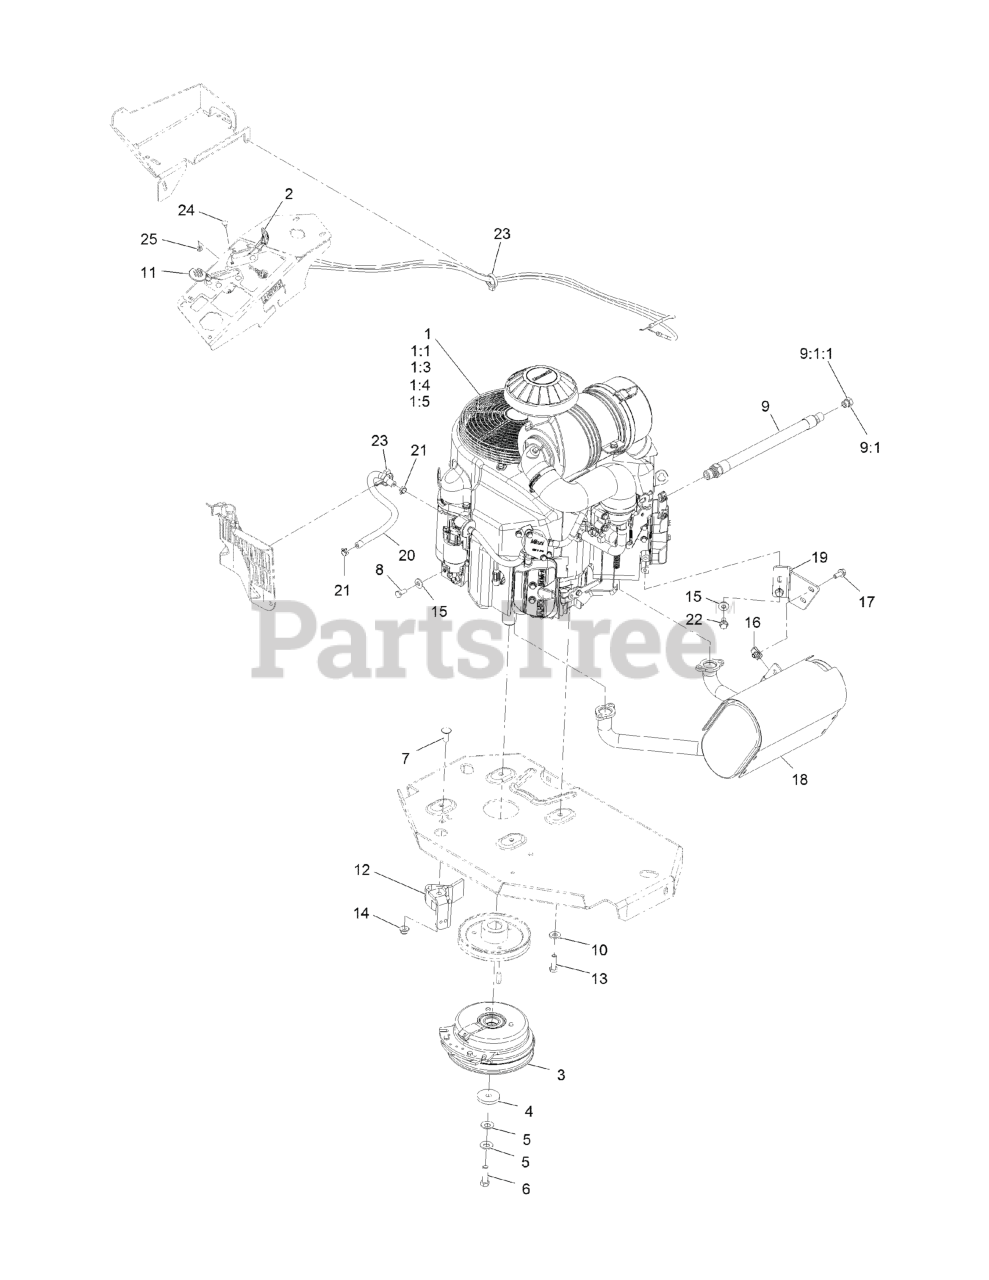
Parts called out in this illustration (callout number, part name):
1:1	Kawasaki 49065-2078 Engine Oil Filter
1:3	Kawasaki 49019-7001 Fuel Filter
1:4	Kawasaki 11013-7039 Safety Filter
1:5	Kawasaki 11013-7038 Air Filter
2	ASM, CHOKE CABLE
3	CLUTCH KIT
4	WASHER-CLUTCH
5	WASHER-SPRING
6	SCREW-HH 7/16-20 X 1 1/2 W/LOCTITE
7	SCREW-CARR
8	SCREW-HH
9	ENGINE OIL DRAIN HOSE ASM
9:1	PLUG-HH
9:1:1	O-RING
10	WASHER-BELLEVILLE
11	ASM,THROTTLE CABLE
12	CLUTCH-ANCHOR
13	SCREW-HH
14	NUT-HF, NI
15	WASHER-SPRING
17	SCREW-HHF
18	MUFFLER
19	BRACKET-MUFFLER
20	HOSE-FUEL
21	CLAMP-HOSE
22	SCREW-HHF
23	CLAMP-HOSE
24	BOLT-CARR
25	NUT-LOCK, NI
